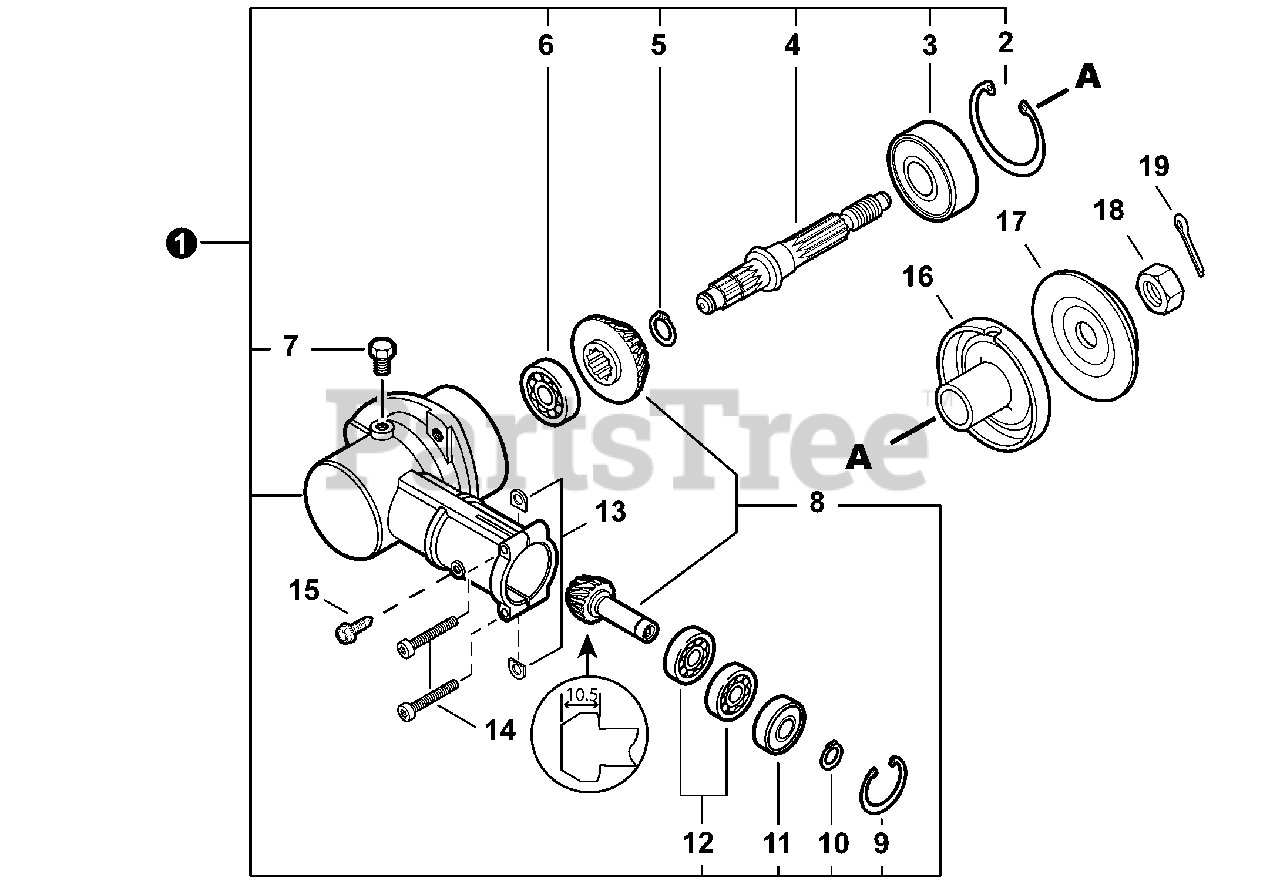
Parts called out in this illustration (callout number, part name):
1	GEAR CASE ASSY
2	RING, SNAP 42
3	BEARING, BALL 6302
4	SHAFT, GEAR
5	RING, SNAP 12
6	BEARING, BALL 629
7	BOLT M8×8
8	GEAR SET
9	RING, SNAP 22
10	RING, SNAP 10
11	BEARING, BALL 6900-Z
12	BEARING, BALL 6900
13	D-WASHER
14	BOLT, TORX 5×25
15	BOLT, 5 SELF DRILLING
16	PLATE, ADAPTOR - UPPER
17	PLATE, ADAPTOR - LOWER
18	NUT 10×1.25 LH
19	PIN, COTTER 2×22
